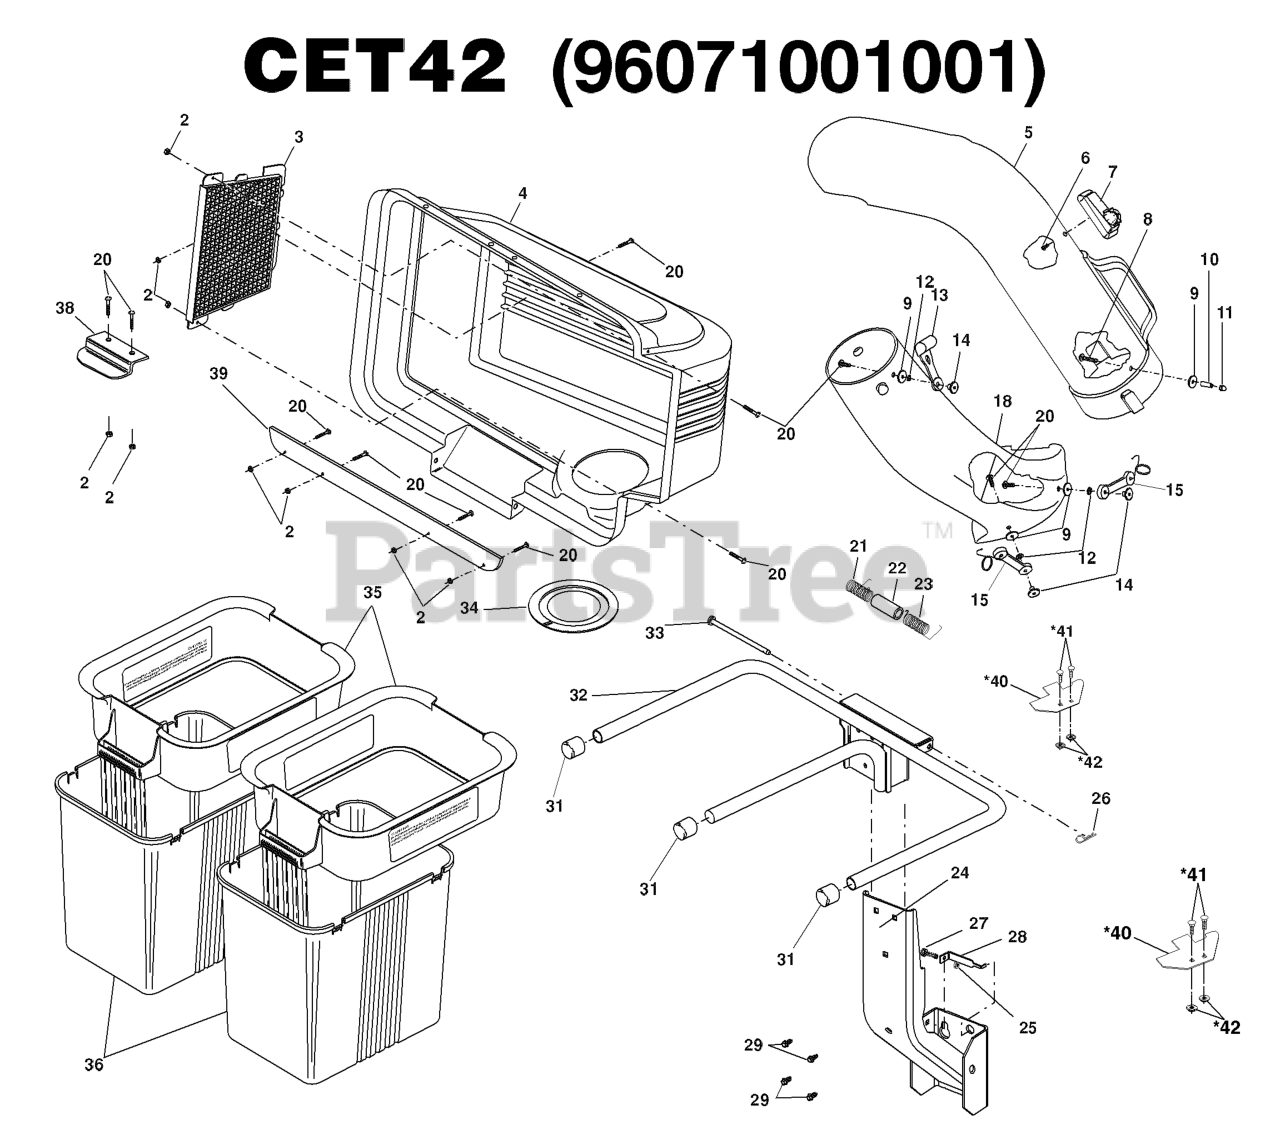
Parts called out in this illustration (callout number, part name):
3	COVER SCREEN
4	COVER.ASM.BAG.W/STRIP
5	CHUTE.UPPER.42"
7	INDICATOR ASM BAG
8	SCREW
9	RP STEEL WASHER
11	NUT
12	LOCKWASHER #10
13	LATCH.HOOD.
14	WELDNUT
15	LATCH ASSY
18	LOWER CHUTE FOR 42" BAGGER
20	SCREW
21	SPRING COVER LH
22	SPACER.COVER.BAGGER
23	SPRING COVER RH
24	POST.SUPPORT.BAGGER.BLACK
25	LOCKNUT.NYLOC.1/4-20
26	RETAINER-SPRNG RB
28	STOP BRACKET, BAGGER 2 BIN
29	SHOULDER BOLT 5/16-18TT
31	PLUG, TUBING END
32	FRAME.ASM.BAGGER.2BIN.QC42B
33	BAGGER.HINGE.PIN
34	GASKET.COVER.BAGGER
35	CONTAINER TOP
36	CONTAINER BOTTOM
38	LATCH CER38
39	STRIP.REINFORCE.BAGGER.2BIN.BL
40	BRACKET.CHUTE.BAGGER.BLACK
41	BOLT
42	NUT T
